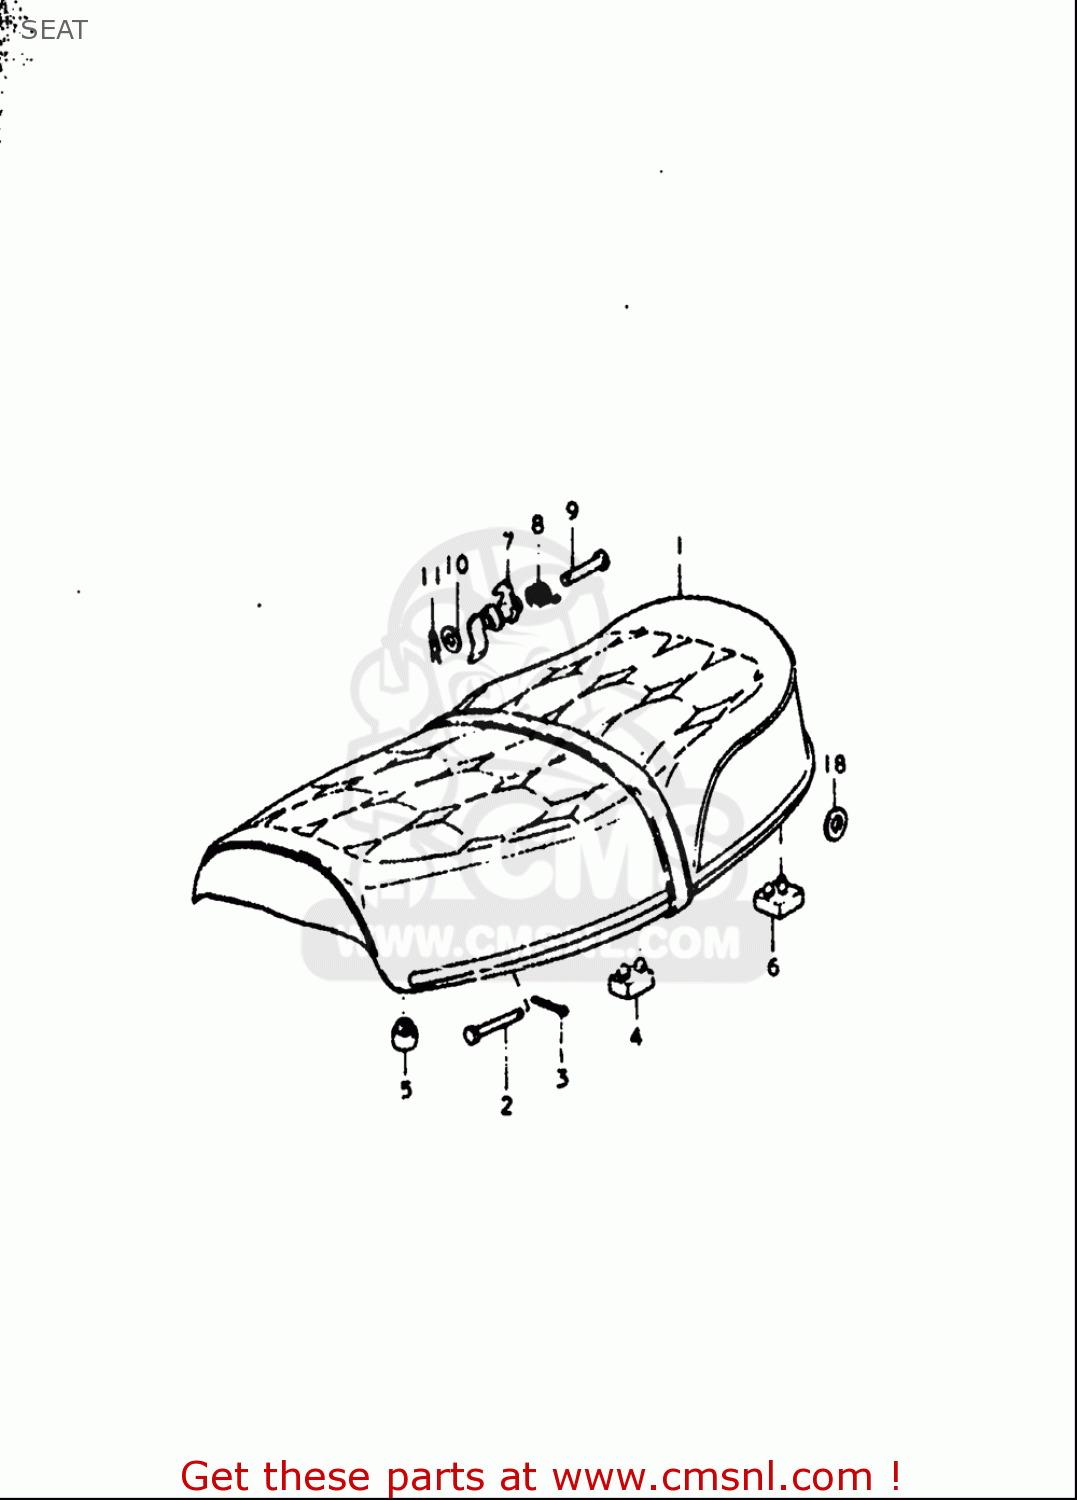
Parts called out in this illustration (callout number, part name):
1	SEAT ASSY
2	PIN
3	PIN
4	CUSHION
5	CUSHION(11.5X22X20)
8	SPRING
9	PIN
10	WASHER
